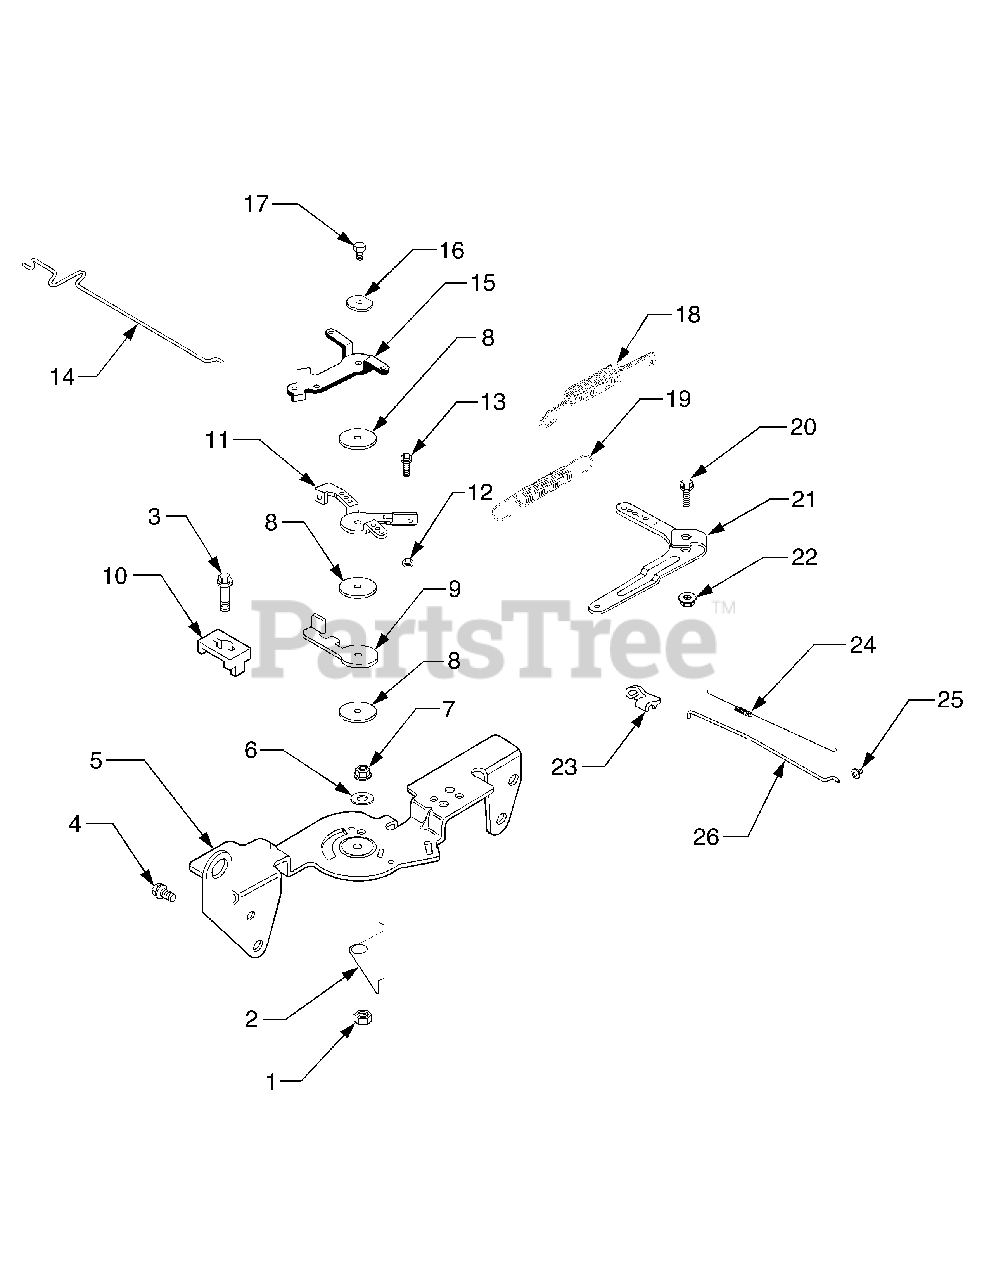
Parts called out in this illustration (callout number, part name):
1	Nut, Hex Lock M5 x 0.8
2	Spring, Choke Return
3	Screw, Hex Flange M5 x 0.8 x 16
4	Screw, Hex Flange M6 x 1.0 x 16
5	Bracket, Control
6	Washer, Lock
7	Nut, Hex Flange
8	Washer , Plain 5.5mm
9	Lever, Throttle Actuator
10	Clamp, Cable
11	Lever, Throttle Control
12	Nut, Hex M4 x 0.7
13	Screw, Hex Cap M4 x 0.7 x30
14	Linkage, Choke
15	Lever, Choke
16	Washer, Spring 1/4"
17	Screw, Hex Flange M5 x 0,.8 x 20
18	Spring, Throttle Limiter
19	Spring, Governor
20	Screw, Round Hd. Square Neck
21	Lever, Governor
22	Nut, Hex Flange M6 x 1.0
23	Bushing, Linkage Retaining
24	Spring, Linkage
25	Bushing, Linkage Retaining
26	Linkage, Throttle
